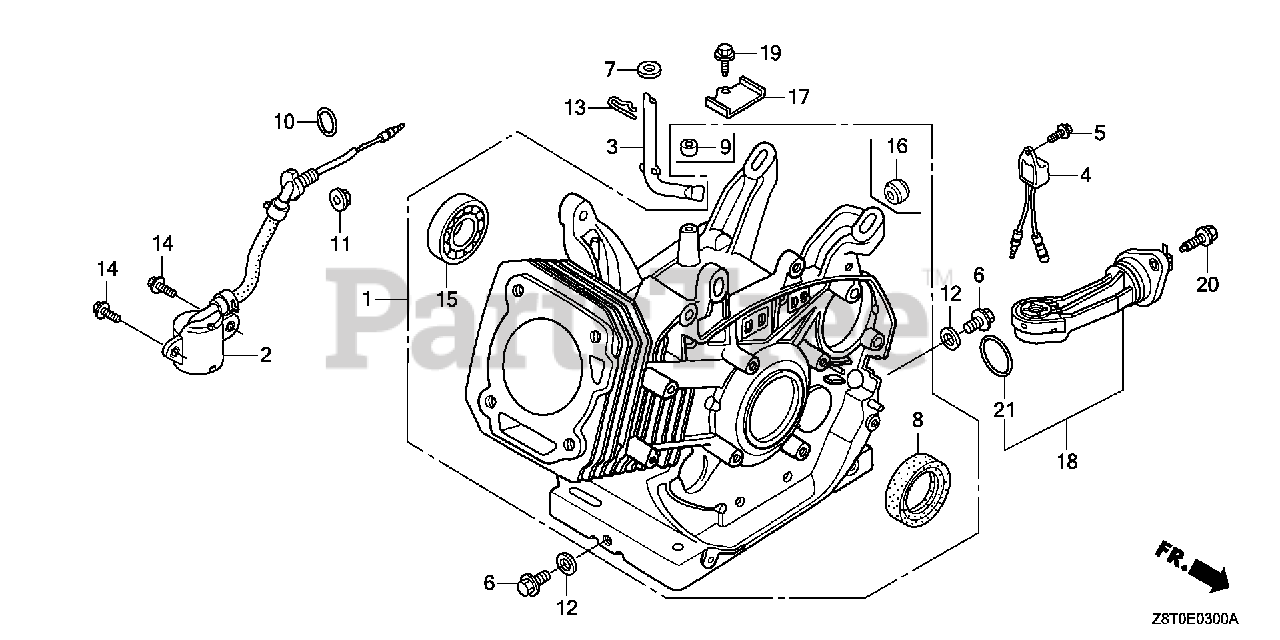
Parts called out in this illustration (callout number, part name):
1	CYLINDER ASSY.
2	SWITCH ASSY., OIL LEVEL
3	SHAFT, GOVERNOR ARM
4	ALERT UNIT, OIL
5	BOLT, FLANGE (6X12) (CT200)
6	BOLT, DRAIN PLUG (12X15)
7	WASHER (8.2X17X0.8)
8	OIL SEAL (35X52X8) (NOK)
9	OIL SEAL (8X14X5)
10	O-RING (13.5X1.5) (ARAI)
10	O-RING (14MM) (NOK)
11	NUT, FLANGE (10MM)
12	WASHER, DRAIN PLUG (12MM)
13	PIN, LOCK (10MM)
14	BOLT, FLANGE (6X12)
15	BEARING, RADIAL BALL (6202)
